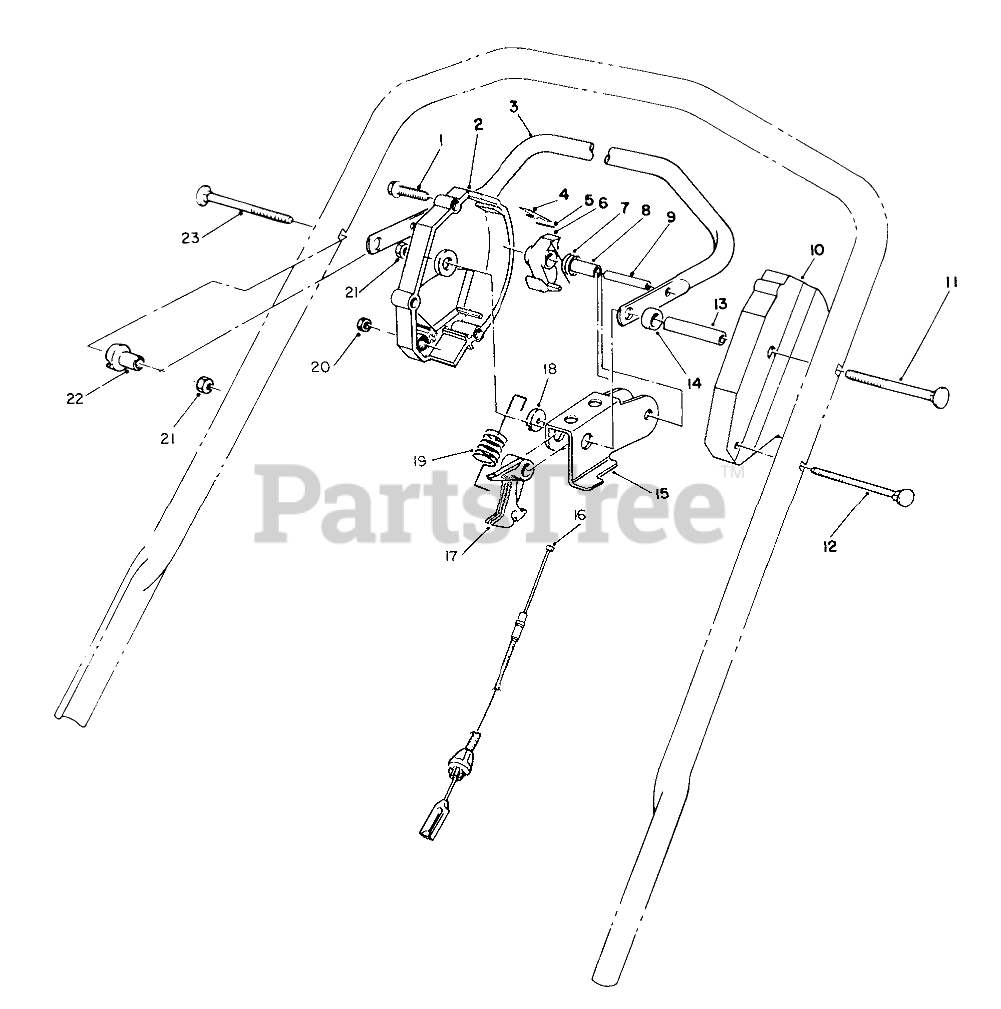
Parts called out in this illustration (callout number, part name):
1	SCREW-HWHTF
2	Housing-Control
3	Bar-Control
4	SPRING-LEAF
5	PIN-INSERT
6	HOOK-CONTROL
7	SPRING-TORSION
8	SPACER
9	PIN-ROLL, SLOTTED
10	HOUSING-CONTROL, LH
11	Screw-Handle
12	HANDLE SCREW
13	TUBING-SPACER
14	SPACER-NYLON
15	ROCKER
16	BBC CABLE ASSEMBLY
17	LEVER-CABLE
18	WASHER-NYLON
19	SPRING-DETENT
20	NUT-HEX
21	NUT-LOCK, NI
22	SPACER-SUPPORT
23	SCREW-HANDLE
